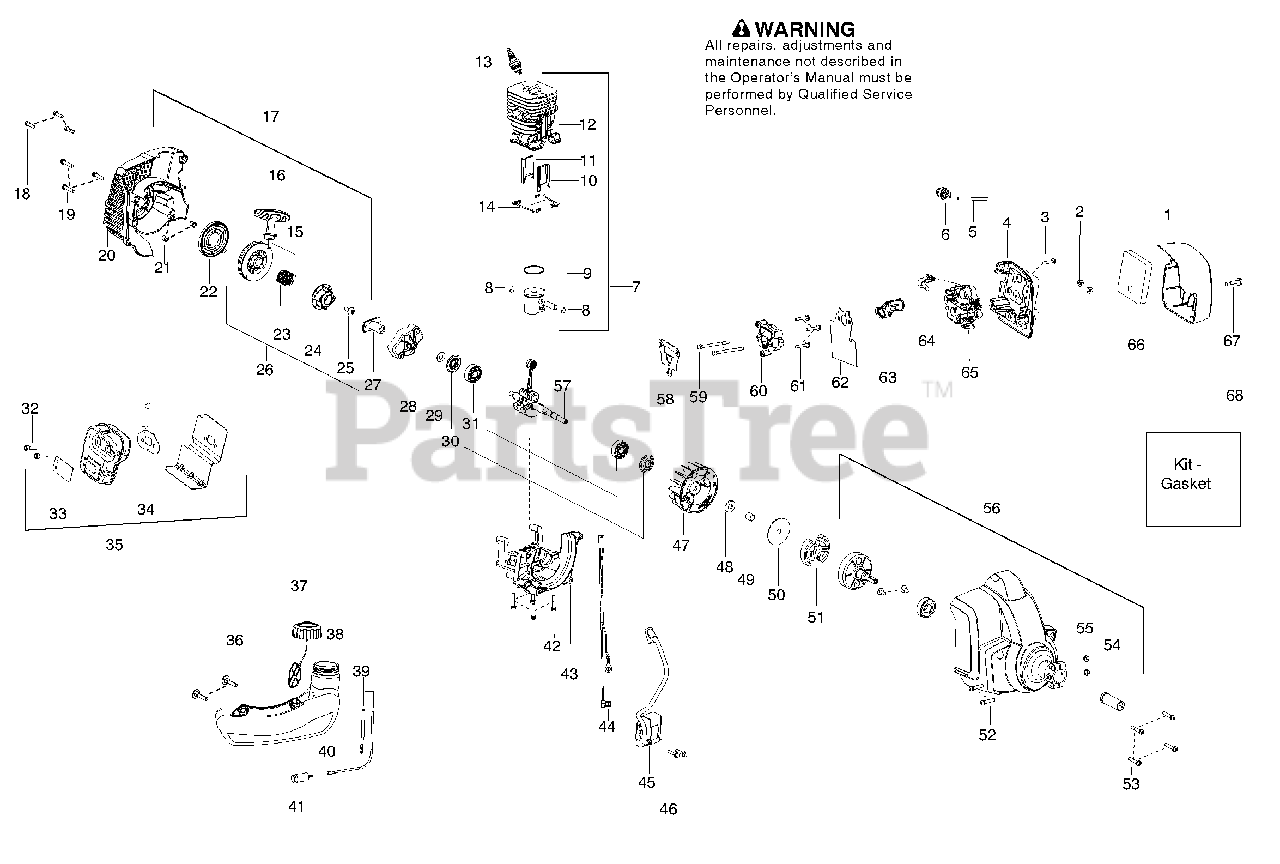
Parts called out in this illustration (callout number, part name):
1	Cover - Airbox
2	Nut - Carb. Screw
3	Screw 8-32
4	Base - Airbox
6	Assy - Purge Bulb
7	Kit - Piston/Cylinder
8	Retainer - Piston pin
9	Ring - Piston
10	Insert - Front Transfer Port
11	Insert - Rear Transfer Port
12	Cylinder - Machined
13	Spark Plug (RCJ- 6Y)
14	Seal - Cylinder (Kit)
15	Kit - Rope
16	Handle - Starter
17	Assy - Starter/Shroud
18	Screw M4 x 1.75
19	Screw m5x25mm
20	Assy - Starter Hsg. w/eyelet
22	Kit - Starter Spring
23	Spring - Starter Hub
24	Hub - Starter
25	Screw m6
26	Kit - Starter Pulley
27	Coupling - Starter
28	Assy - Starter Cup
29	Washer - Flat
30	Seal - Crankshaft (kit)
31	Bearing - Crankshaft
32	Bolt - Muffler
33	Kit - Spark Arrestor
34	Gasket - Muffler (kit)
35	Assy - Muffler
36	Screw - Tank Retainer
37	Assy - Fuel Cap w/ret.
38	Assy - Tank
39	Kit - Fuel line
40	Fitting - Fuel Line
41	Assy - Fuel Pickup
42	Screw - m5x25mm
43	Crankcase
44	Assy - Leadwire
45	Module - Ignition
46	Screw 8-32
47	Flywheel
49	Spacer - Flywheel
50	Washer - Clutch
51	Kit - Clutch Assy.
52	Screw 10-24 x 1"
53	Screw M5 x 25mm
54	Guide - Clutch Drum
55	Locknut 10-24
56	Assy - Fan Housing
57	Kit - Crankshaft Assy.
58	Gasket - Adapter/Cyl. (kit)
59	Bolt M5 x .80
60	Adaptor - Carburetor
61	Screw .20 x 32
62	Gasket - Carb./Adapter(kit)
63	Boot - Carb.
64	Lever - Choke
65	Kit - Carburetor
66	Filter - Air
67	Bolt - Knob
68	Kit - Gasket
